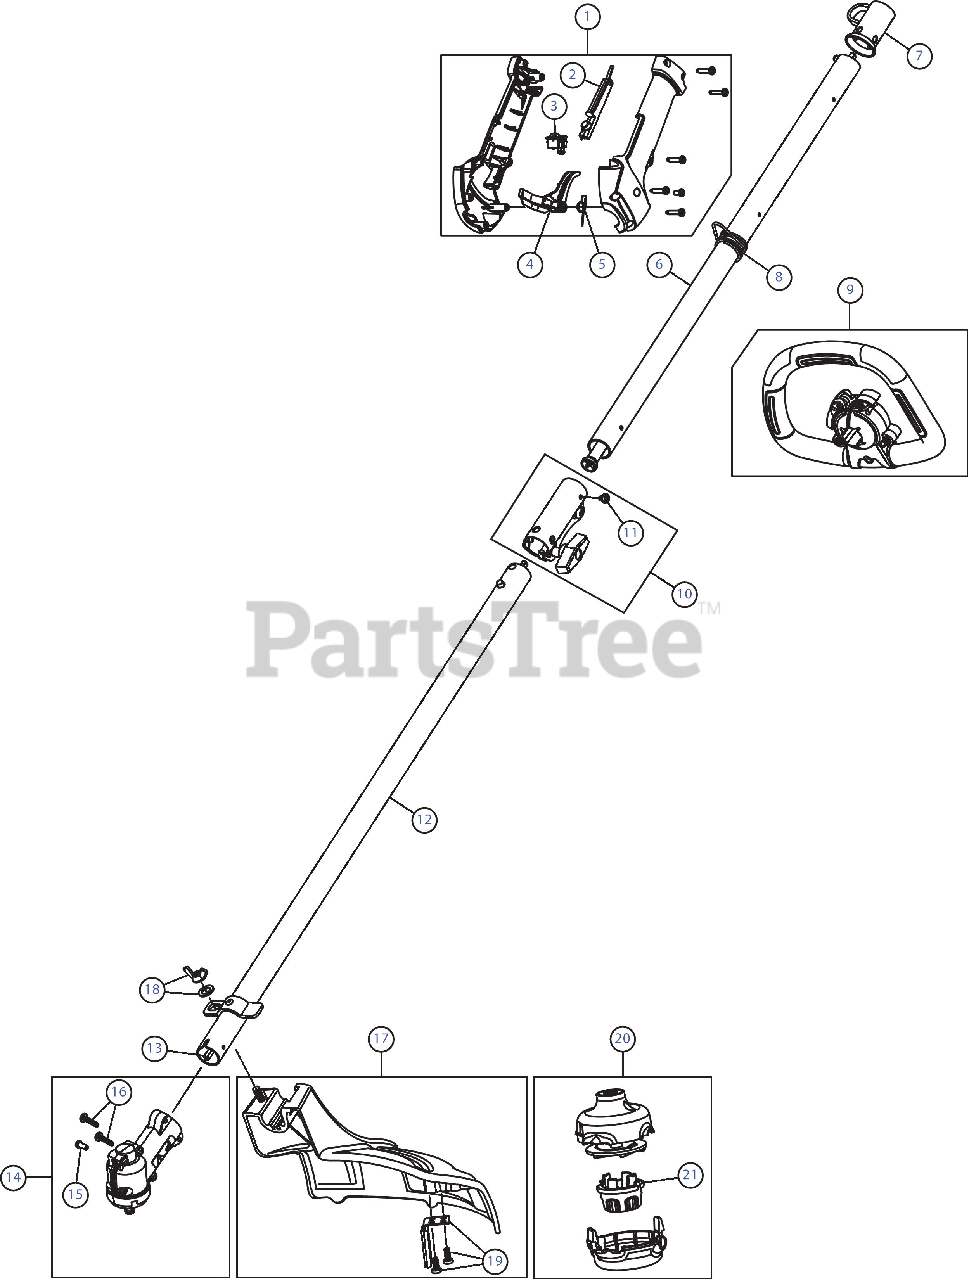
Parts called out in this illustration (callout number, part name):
1	Throttle Housing Assembly (includes 2 - 5)
2	Throttle Trigger Lock-Out
3	Trigger Switch Assembly
4	Throttle Trigger Spring
5	Throttle Trigger
6	Upper Drive Shaft Assembly
7	Hanger
8	Shoulder Strap Clip
9	Handle
10	Split Boom Coupler (includes 11)
11	Coupler Anti-Rotation Screw
12	Lower Drive Shaft Housing
13	Lower Flexible Drive Shaft
14	Gearbox Assembly (includes 15 & 16)
15	Gearbox Anti-Rotation Screw
16	Gearbox Screw
17	Shield Assembly (includes 18 & 19)
18	Shield Mounting Hardware
19	Blade Assembly
20	Cutting Head Assembly
21	Bump Knob
